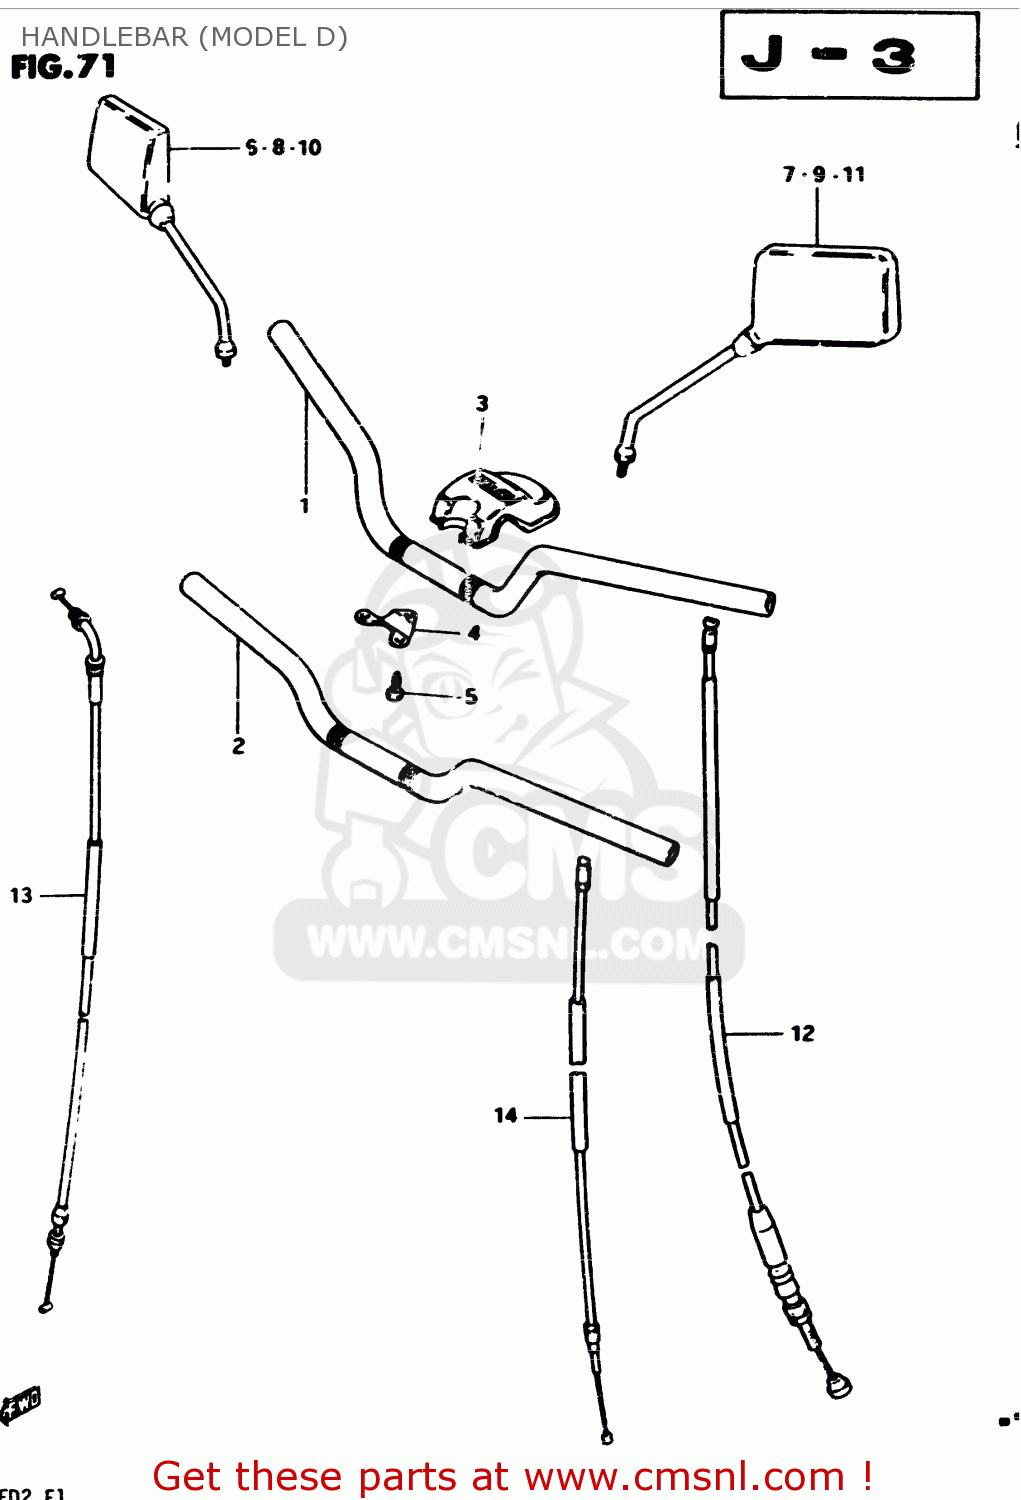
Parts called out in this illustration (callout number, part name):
1	HANDLEBAR
2	HANDLEBAR (FLAT HANDLEBAR)
3	COVER,STEERING HEAD
4	BRACKET,HEAD COVER
5	SCREW
6	MIRROR ASSEMBLY,REAR VIEW
7	MIRROR ASSEMBLY,REAR VIEW
8	MIRROR, REAR VIEW RH
9	MIRROR, REAR VIEW LH
10	MIRROR, REAR VIEW RH
11	MIRROR, REAR VIEW LH
12	CABLE ASSY,CLUTCH
13	CABLE ASSEMBLY,THROTTLE
14	CABLE, THROTTLE
